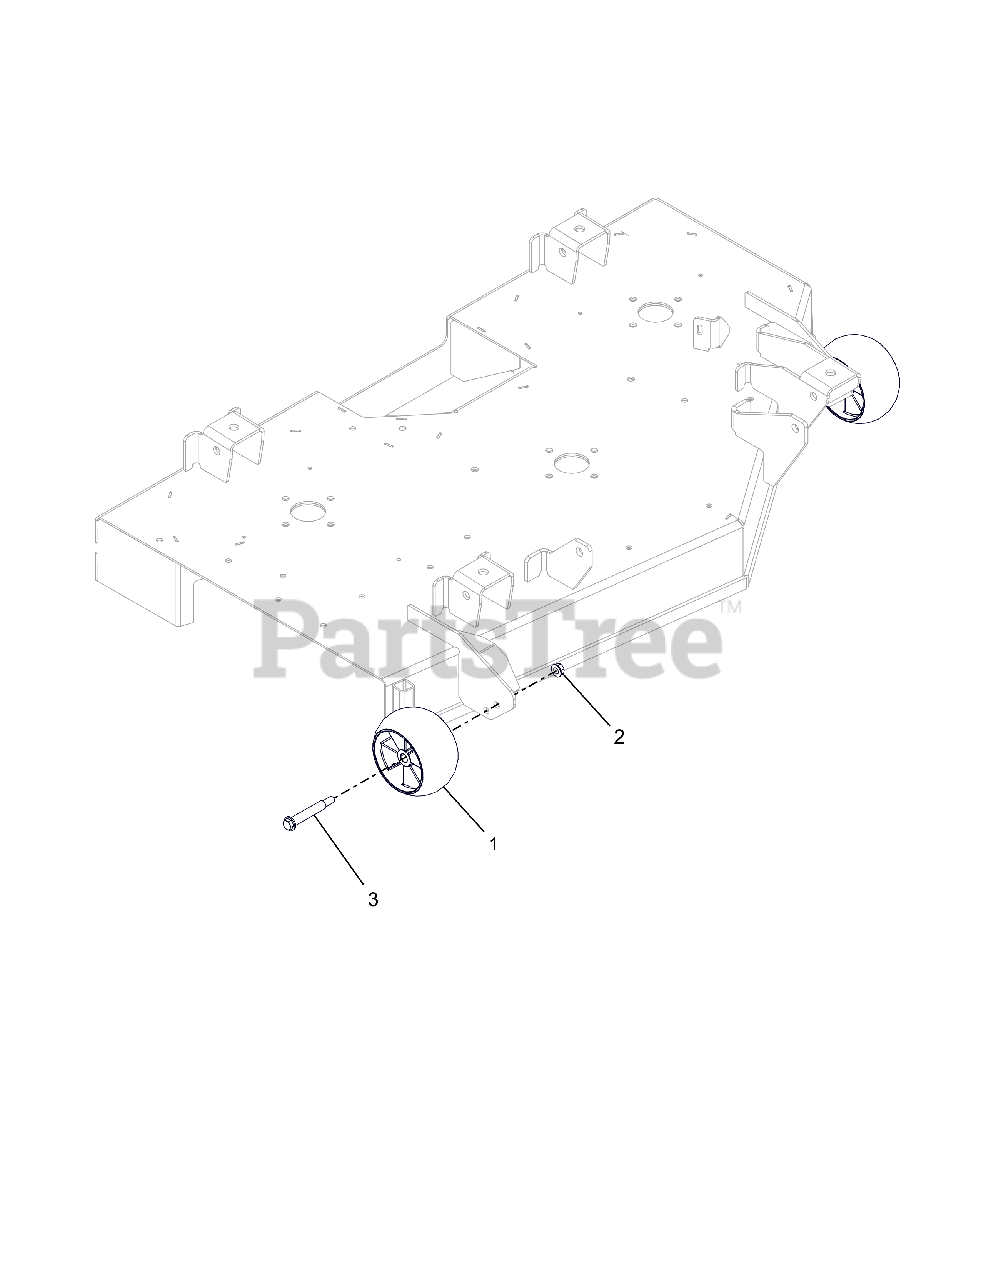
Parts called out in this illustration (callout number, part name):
1	ANTI-SCALP WHEEL - 5X OS
2	NUT-LK-TOP-FLG .38-16 ZC120
3	BLT-SHLDR .38-16X2.50 HWH G5
